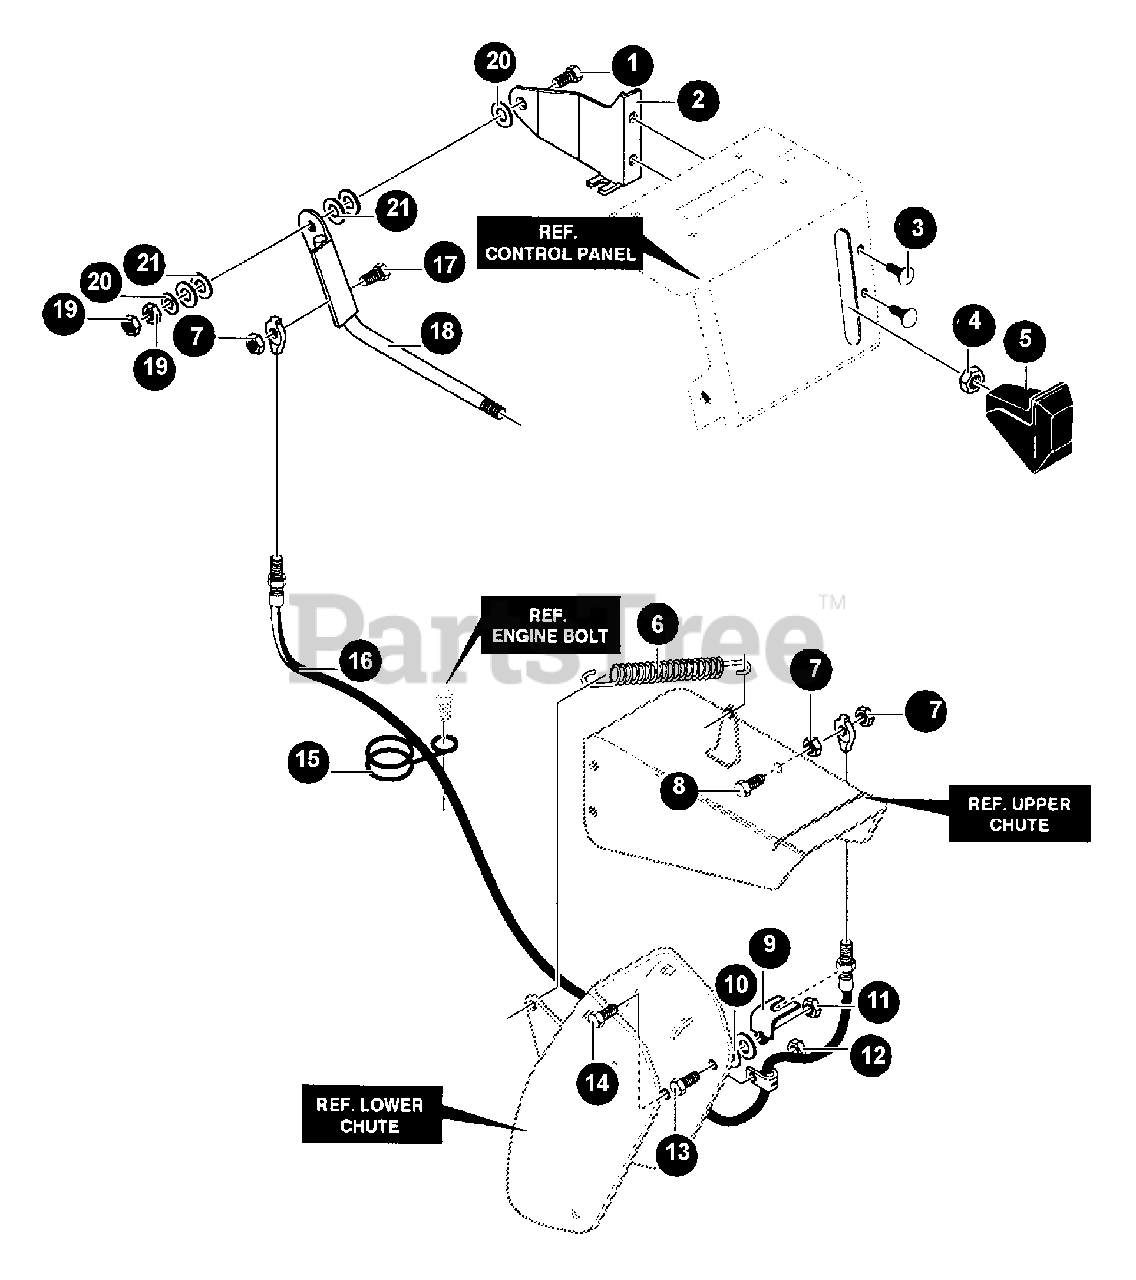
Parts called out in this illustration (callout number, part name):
1	SCREW - 3/8-1 6X 1.75"
2	BRACKET, REMOTE CHUTE
3	SCREW - 1/4-20 X .63" -- TAPPING
4	NUT - 3/8-16
5	KNOB, SHIFT
6	SPRING
7	NUT - 1/4-20
8	SCREW - 1/4-20 X 1"
9	BRACKET, CABLE CHUTE
10	WASHER
11	NUT - 5/16-18
12	LOCKNUT - 10-24
13	SCREW - 5/16-18 X 3/4"
14	SCREW - 10-24 X 3/8"
15	WIRE, FORM
16	CABLE, REMOTE
17	SCREW - 1/4-20
18	HANDLE ASSY
19	LOCKNUT - 3/8-16
20	WASHER
21	WHEEL - 6X1.5
